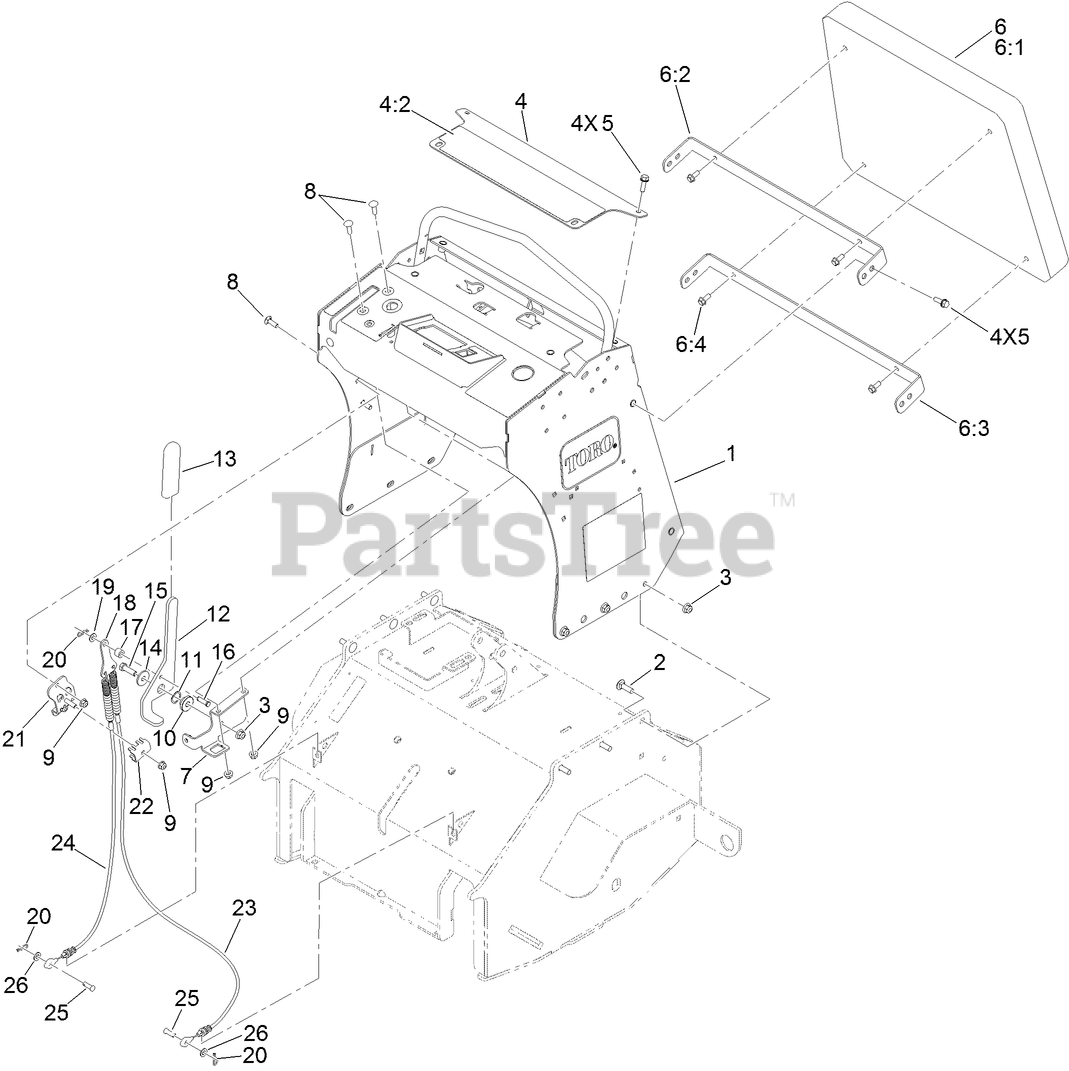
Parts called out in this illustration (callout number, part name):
1	CONTROL TOWER ASM
2	BOLT-CARR
3	NUT-HF, NI
4	CONTROL PANEL ASM
4:2	DECAL-WARNING
5	SCREW-HHF
6	CUSHION ASM
6:1	CUSHION-BLACK
6:2	BRACKET-PAD, UPPER
6:3	BRACKET-PAD, LOWER
6:4	SCREW-HHF
7	BRACKET-PIVOT, BRAKE
8	SCREW-CARR
9	NUT-HF, NI
10	PIVOT-FLANGE
11	WASHER-WAVE
12	HANDLE-BRAKE
13	GRIP-LEVER
14	WASHER
15	SCREW-HH
16	PIN-YOKE
17	BUSHING
18	YOKE-CABLE
19	SPACER-NYLON
21	MOUNT-CABLE, BRAKE
22	CLAMP-CABLE
23	CABLE-BRAKE, LH
24	CABLE-BRAKE, RH
25	PIN-CLEVIS
26	WASHER-PLAIN
